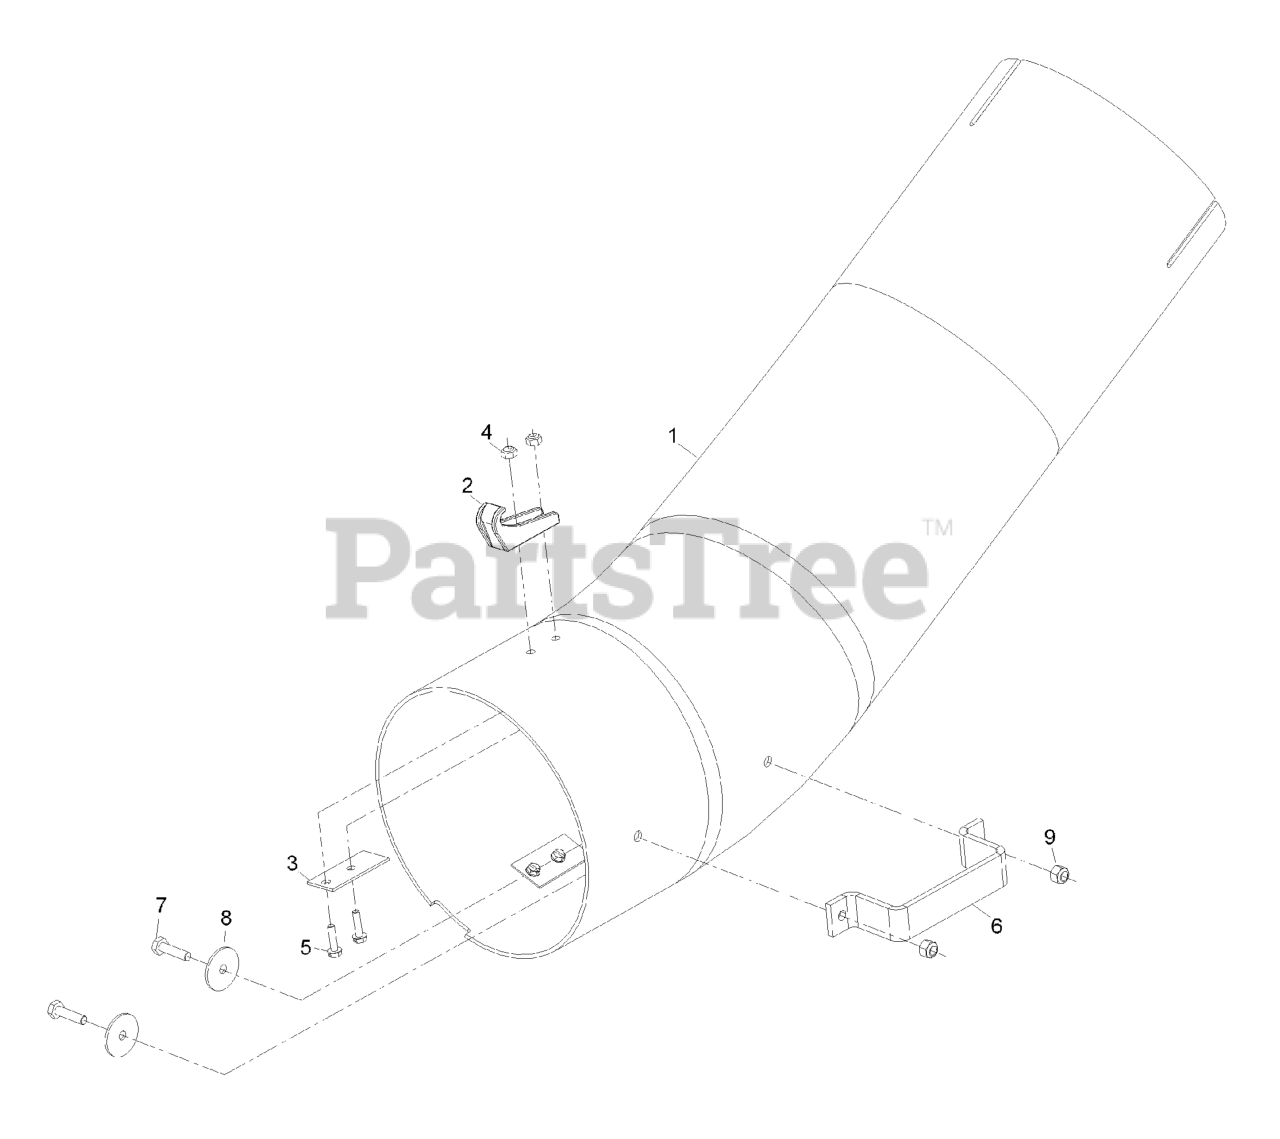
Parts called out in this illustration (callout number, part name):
2	LATCH-CATCH
3	PLATE-BACKING
4	TUBE-LOWER
5	SCREW-HH
6	WASHER-FLAT
7	NUT-LOCK, NI
8	NUT-LOCK, NI
9	SCREW-HWH
